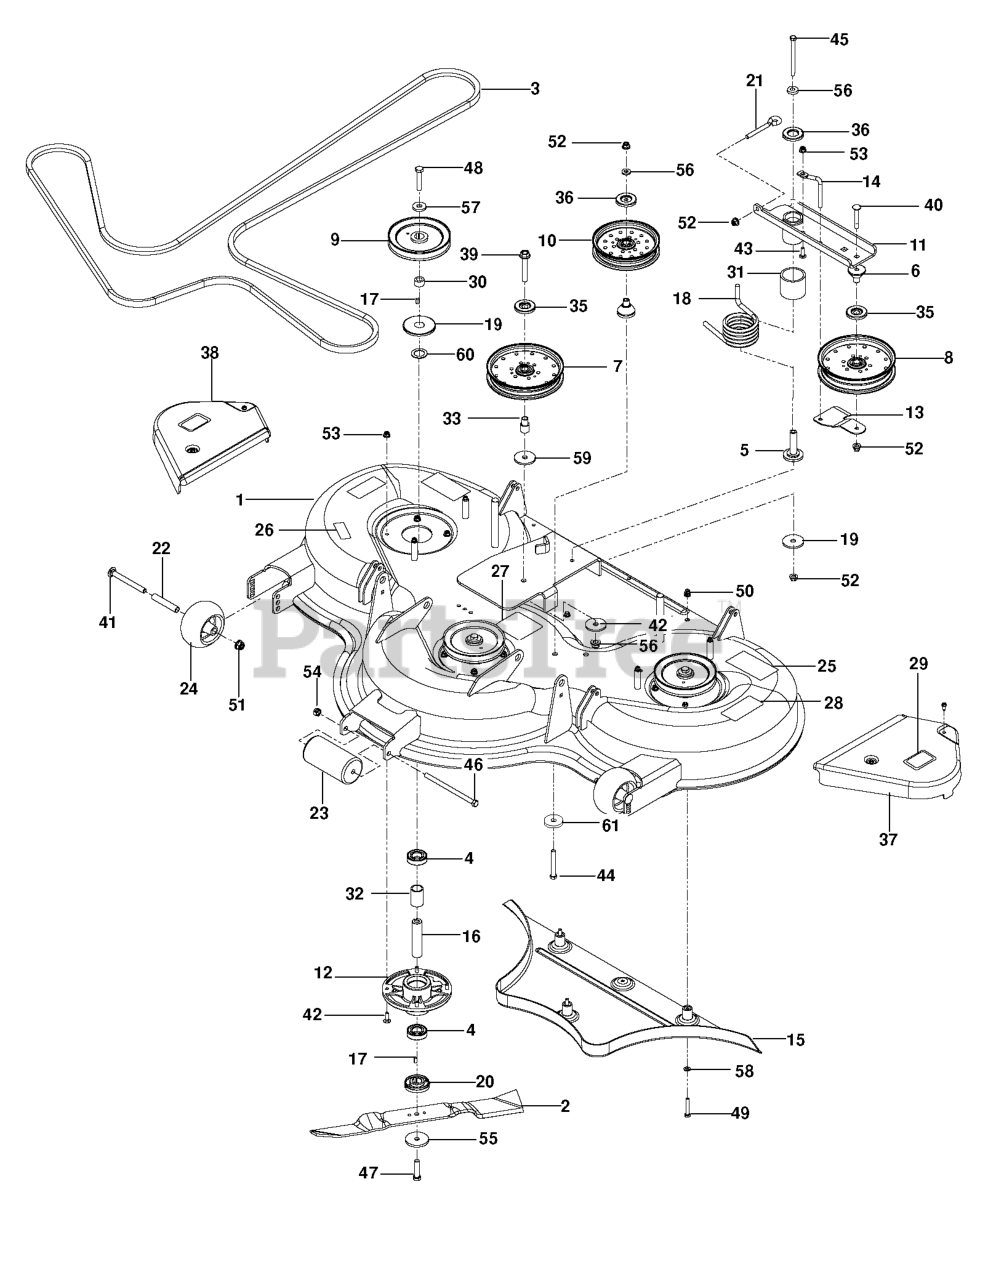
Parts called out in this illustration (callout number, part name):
1	DECK W/SAFETY DECALS
3	BELT, DECK
4	BALL BEARING
5	BEARING, IDLER PIVOT
6	BEARING, IDLER ARM
7	PULLEY - 7" NARROW
8	PULLEY - IDLER 7"
9	PULLEY, 61
10	PULLEY IDLER, 6" NARROW
11	ASSY, IDLER ARM, PZ
12	BEARING HOUSING
13	BELT.GUIDE.BLACK
14	BELT KEEPER
15	PLUG ASSEMBLY
18	SPRING, TORSION, IDLER
19	TOP DUST CAP
20	BUSHING, BLADE
21	EYE BOLT, 3/8 X 4"
22	TUBE, ROLLER AXLE
23	ROLLER
24	ROLLER, GAUGE .635 BORN
25	DECAL, EURO SEVERING
26	DECAL, 155
27	DECAL, BELT ROUTING
28	DECAL, BELT DRIVE
29	DECAL, NO STEP
30	KEY RETAINER
31	SPACER, IDLER PIVOT
33	SPACER - IDLER
35	SHIELD, DUST
36	DUST SHIELD
37	BELT SHIELD LT
38	BELT SHIELD RT
39	HFFS 1/2-13 X 3 GD 5 ZD
40	CARRIAGE BOLT 3/8-16 X
41	RHSNB 1/2-13 X 4.75 GR5 ZD
42	RHSNB 5/16C X 1
43	RHSSNB 5/16C X 1.0
44	SCREW 3/8C X 2 3/4 HEX CAP
45	HCS 3/8-16 X 4-1/2 GR 8 ZD
46	HCS 7/16-14 X 7 GR5 ZD
47	HCS M12 X 1.75 X 50 GR8.8 ZD
48	HCS M12 X 1.75 X 60 GR5 ZD
49	HCS M8 X 1.25 X 50 GR8.8 ZD
50	BLIND RIVET NUT
51	NUT, 1/2-13 HEX FLG NYLOC ZD
52	NUT 3/8-16 HEX FLG NYLOC ZD
53	5/16-18 NYLOC FLANGE NUT
54	NUT 7/16C CENTERLOCK
56	WASHER, 3/8 THICK
57	WASHER-.533IDX1.37OD
58	FLAT WASHER 5/16 SAE
59	WASHER, HEAVY
60	WASHER-1.06IDX1.63ODX.06
61	SPINDLE WASHER
